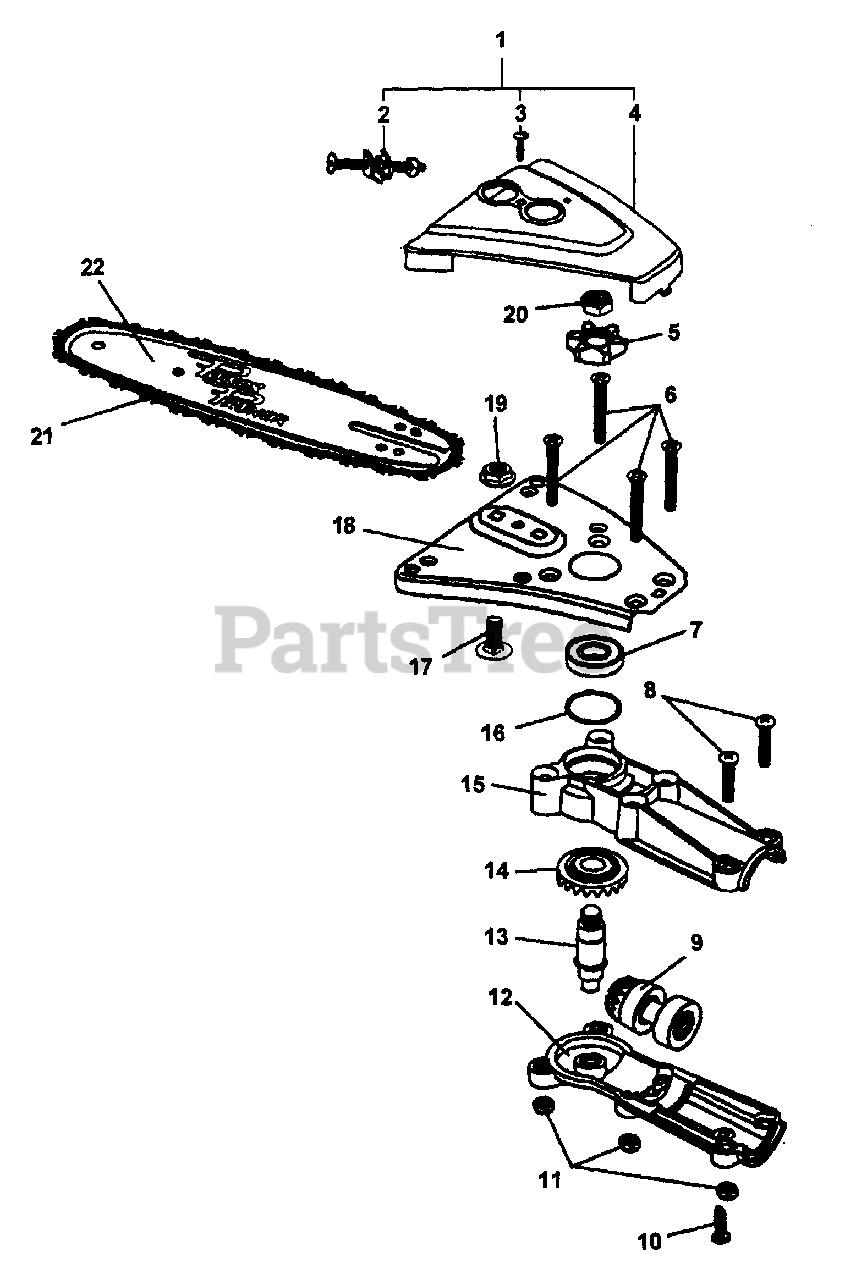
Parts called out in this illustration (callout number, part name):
1	SPROCKET COVER ASSY
2	TENSIONER KIT
3	SCREW - 8-32 X 1"
4	GUARD, SPROCKET
5	SPROCKET
7	BEARING, BALL - 6001 DDU
8	SCREW - 10-24 X 1-1/4"
9	SHAFT GEAR ASSY
10	SCREW
11	LOCKNUT - 10-24
12	CASE, GEAR - RIGHT
13	SHAFT GEAR ASSY
14	GEAR - BEVEL
15	CASE, GEAR - RIGHT
16	SHIM .004"
17	BOLT
18	SAW BAR CARRIER
19	NUT - FLANGE
21	SAW CHAIN - 8" (20cm)
22	GUIDE BAR - 8" (20cm)
